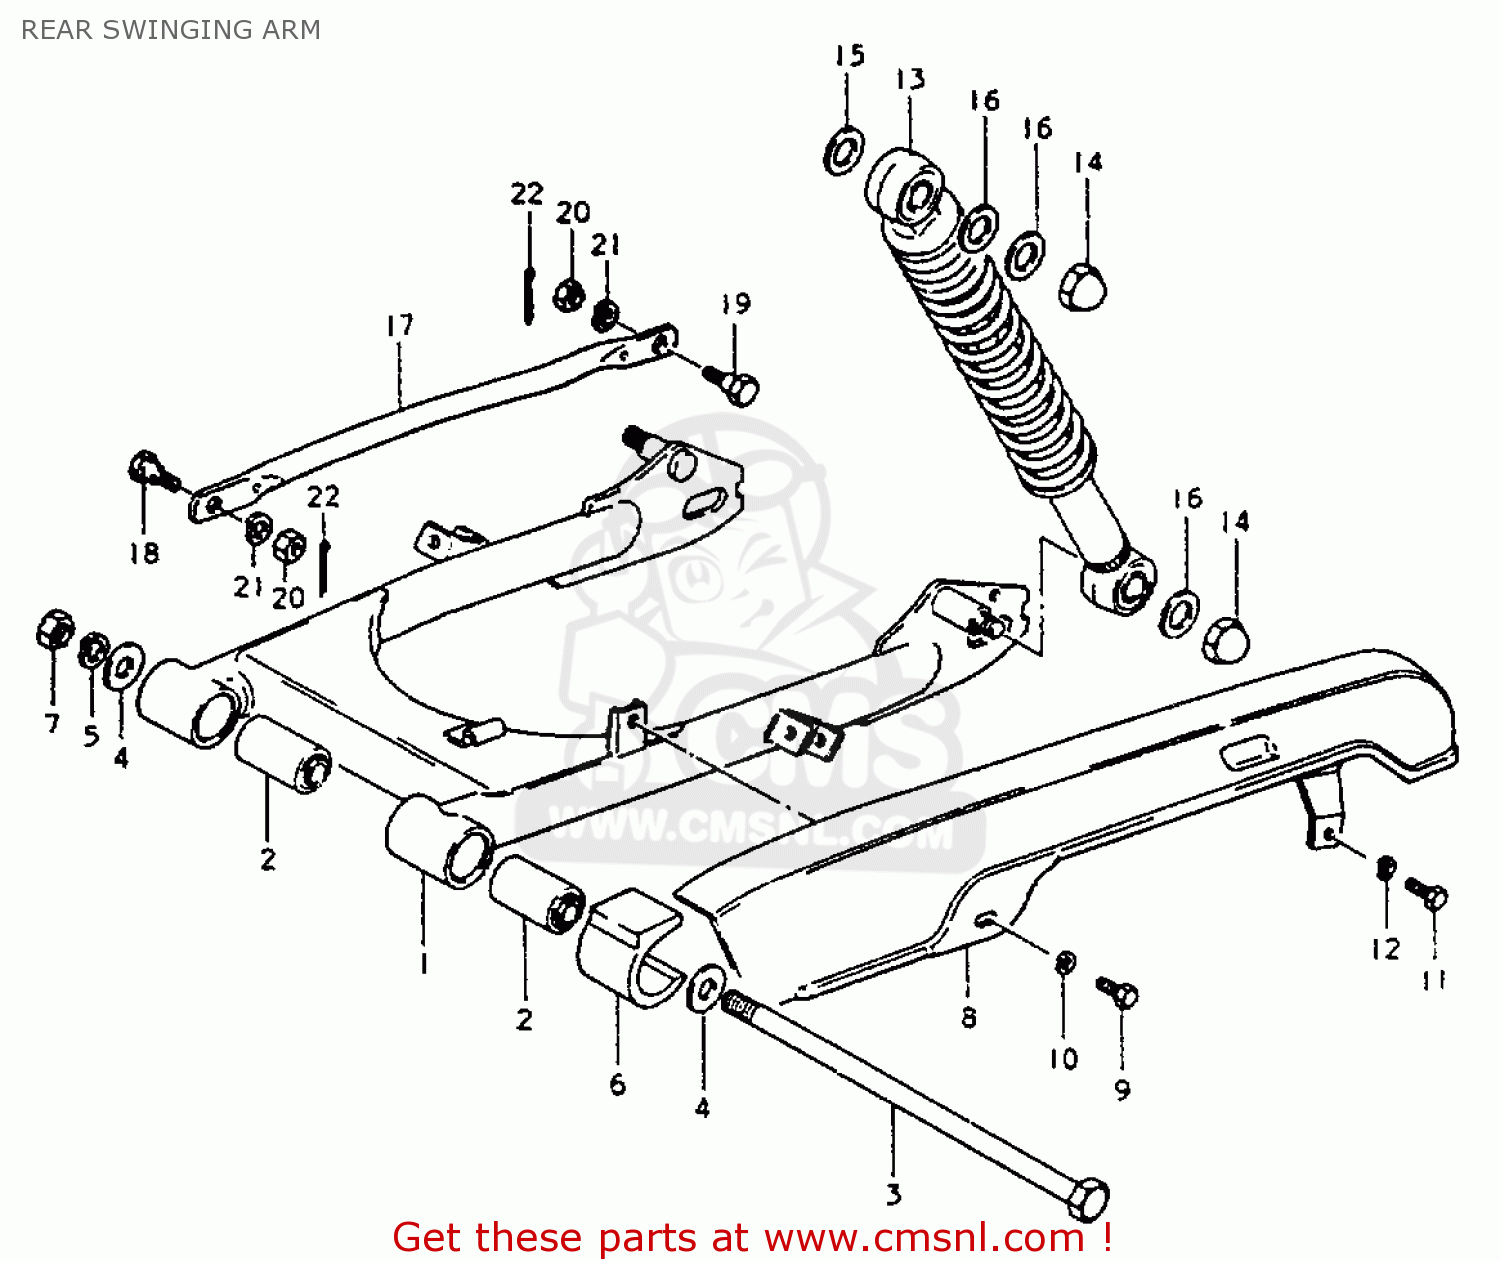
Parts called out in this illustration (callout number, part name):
1	SWINGING ARM SET (BLACK)
2	BUSH
3	SHAFT,RR SHOCK ABSORBER UPR
4	WASHER
5	LOCK WASHER
6	BUFFER,CHAIN TOUCH DEFENSE
7	NUT
8	CHAIN CASE
9	BOLT
10	LOCK WASHER
11	BOLT, UPPER
12	LOCK WASHER
13	SHOCK ABSORBER, REAR
14	NUT
15	WASHER
16	WASHER
17	TORQUE LINK, REAR
18	BOLT(8X22)
19	BOLT(8X26.5)
20	NUT
21	LOCK WASHER
22	PIN
